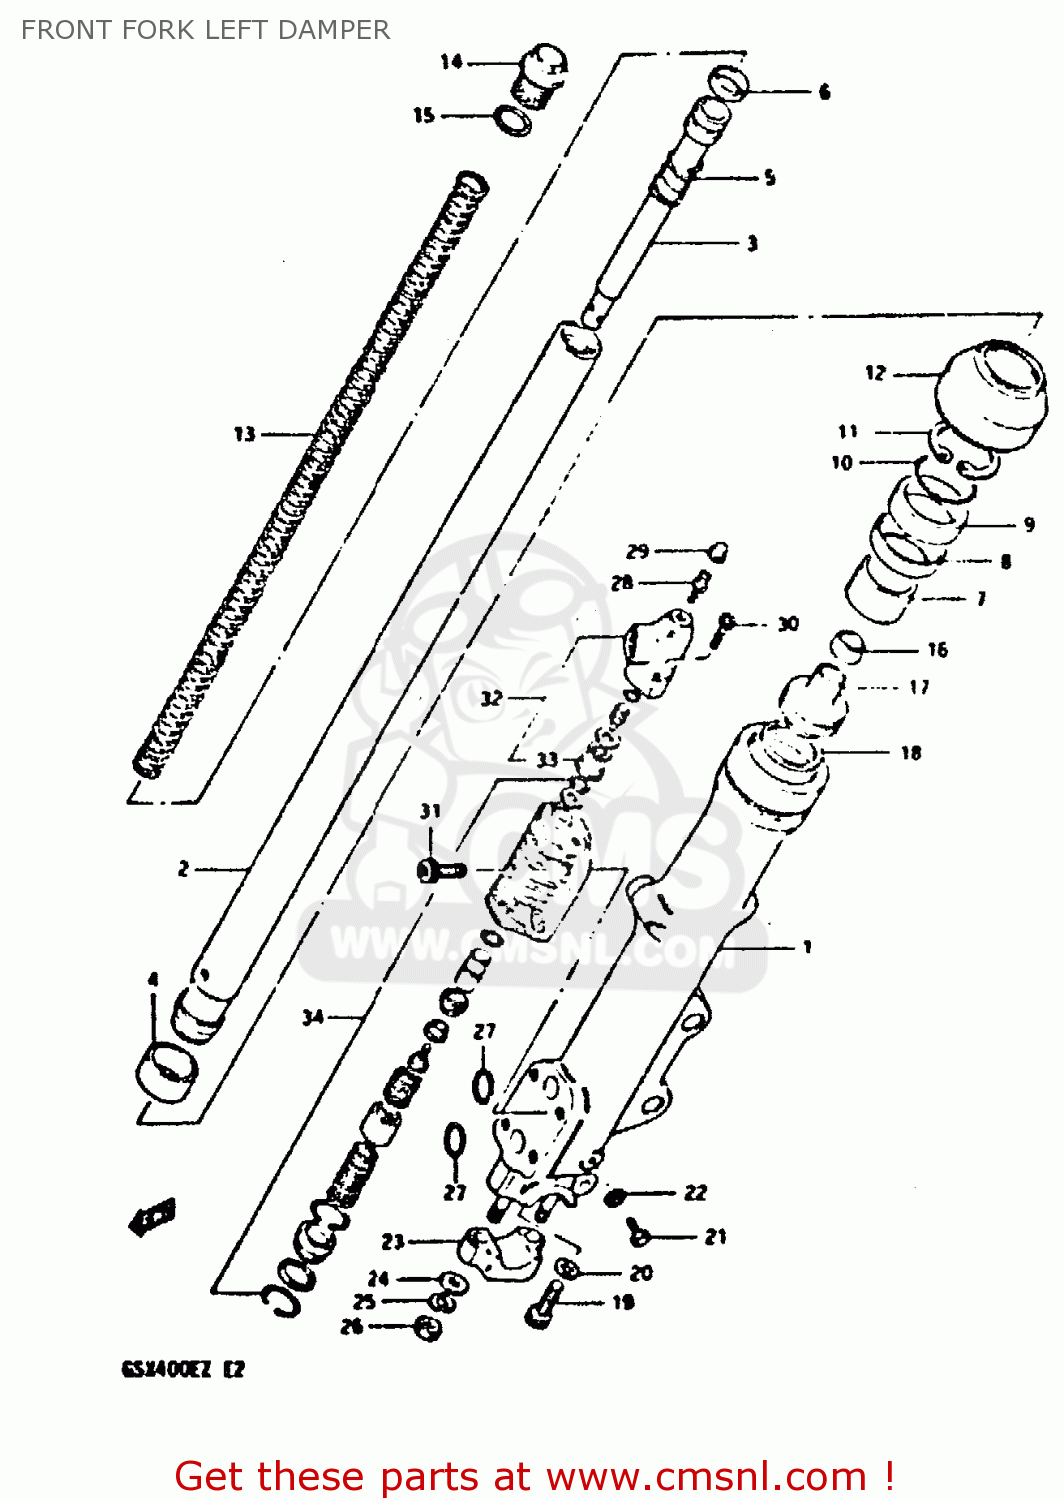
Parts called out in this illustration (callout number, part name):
1	OUTER TUBE LH
2	INNER TUBE,L
3	CYLINDER, LH
4	BUSH
5	SPRING,REBOUND
6	RING,PISTON
7	BUSH,GUIDE
8	SPACER,OIL SEAL
9	OIL SEAL,FRONT FORK
10	RING,BACKUP
11	RING,OIL SEAL STOPPER
12	DUST SEAL
13	SPRING,FR.FORK
14	BOLT
15	O RING
16	VALVE,OIL LOCK PIEACE
17	PIECE,OIL LOCK
18	RING, PISTON
19	BOLT(8X27)
20	GASKET (NAS)
21	BOLT
22	GASKET,DRAIN,PLUG (NAS)
23	HOLDER,AXLE
24	WASHER
25	LOCK WASHER
26	NUT
27	O RING,FR FORK
28	BREATHER
29	CAP
30	BOLT
31	BOLT
32	MODULATOR PARTS SET,FRONT
33	SEPARATOR,FRONT FORK MODULATOR
34	MODULATOR VALVE SET
